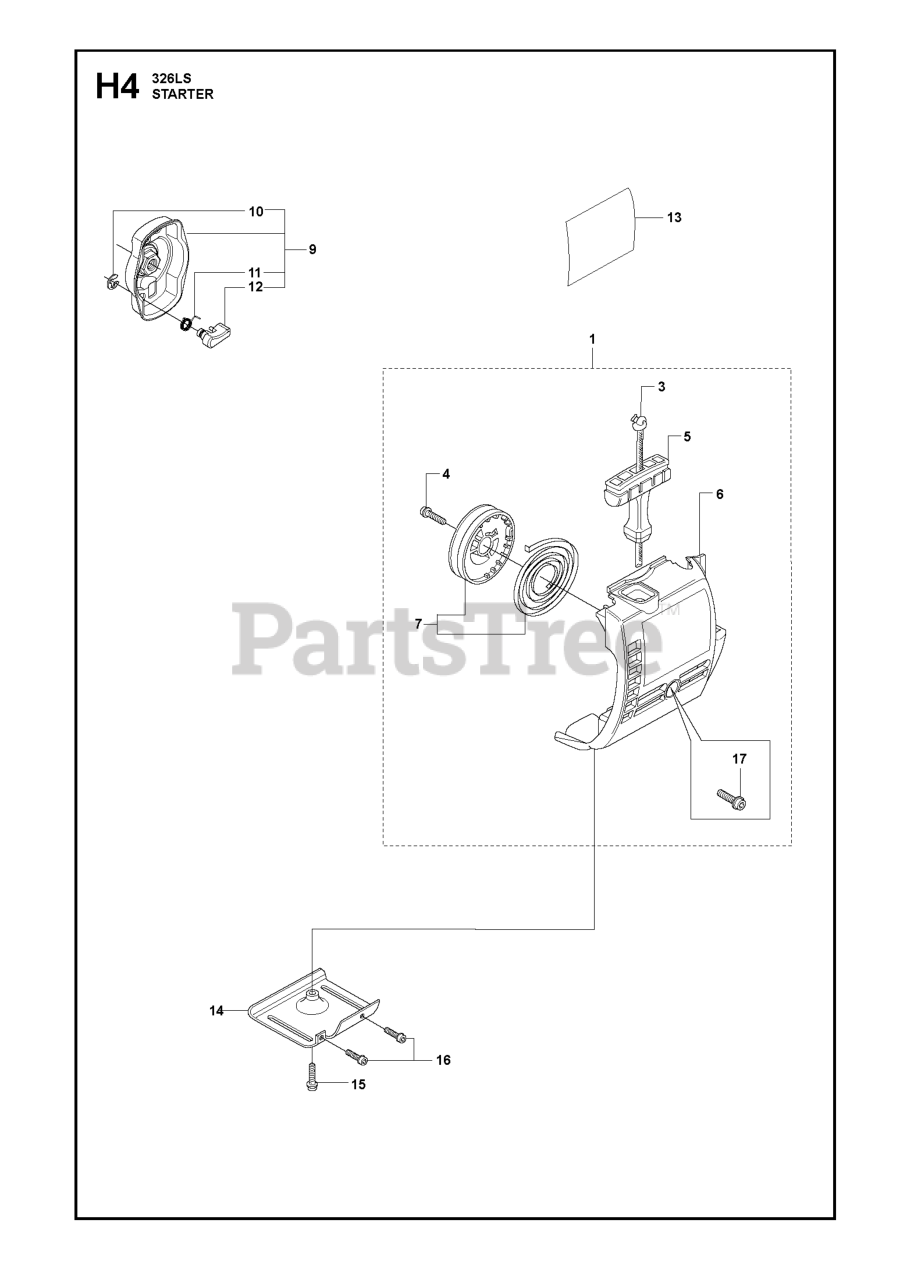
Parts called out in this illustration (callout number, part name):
2	VALVE STEM LT
3	TIRE HEAVY DUTY
4	TUBE.5.3/4.5/6
5	RIM ASM 6" FRONT SILVER
6	FITTING LT
7	BEARING T
8	RIM ASM 8" REAR SILVER
9	TIRE
10	TUBE
11	CAP.HUB.FRONT.LT.BLACK
